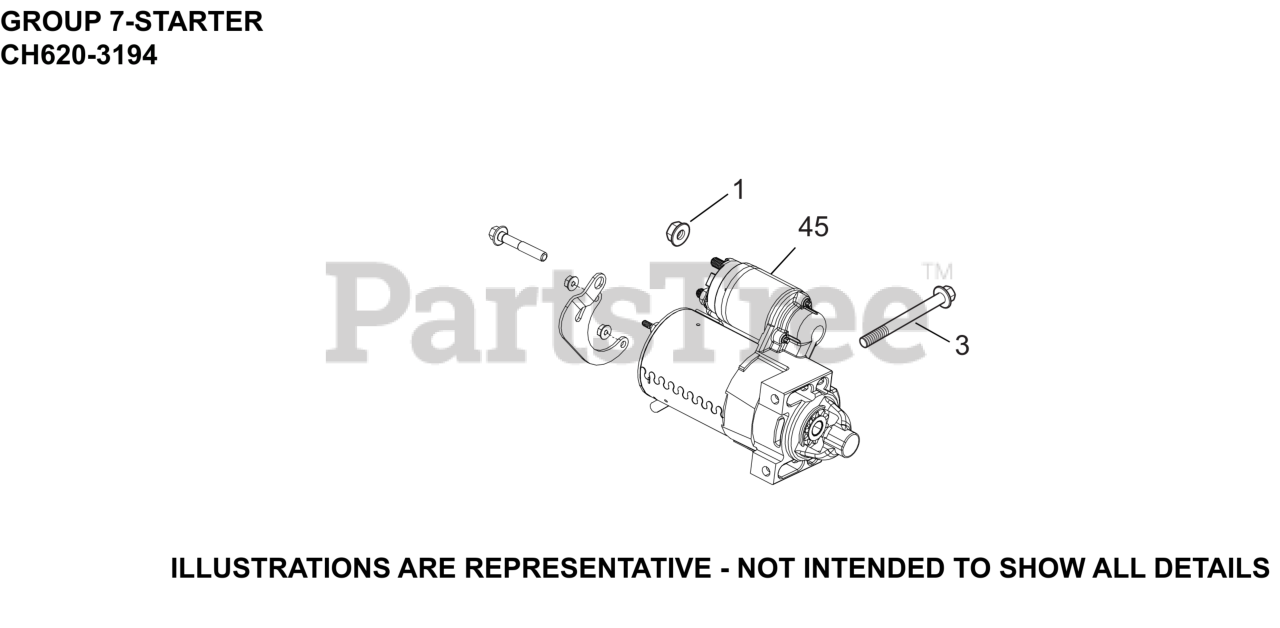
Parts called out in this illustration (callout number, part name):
1	NUT, FLG M8X1.25
3	SCREW, FLG M8X1.25X80
45	STARTER, SOLENOID SHIFT (25 098 09-S)
